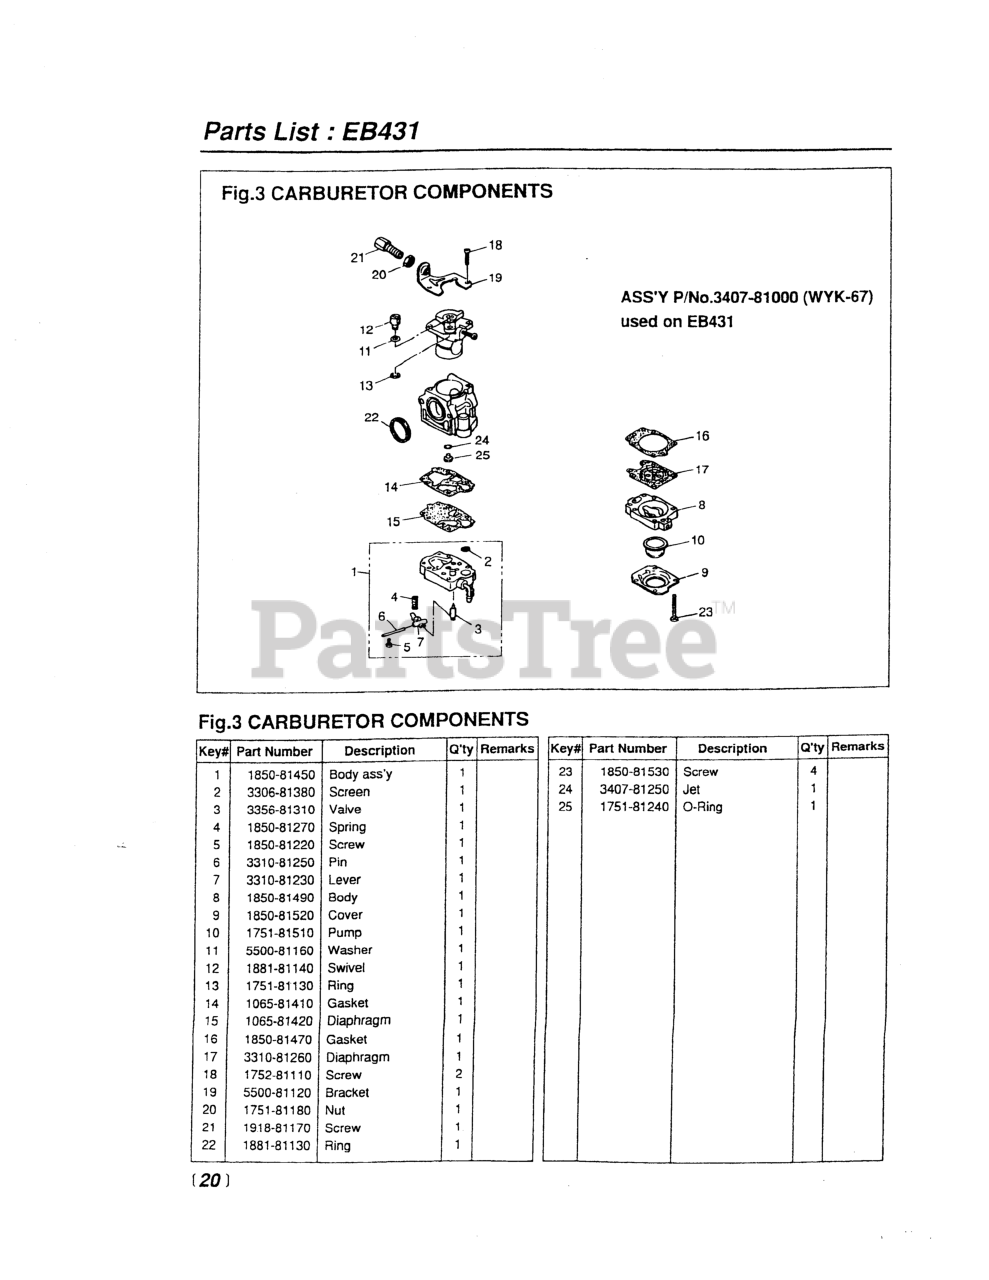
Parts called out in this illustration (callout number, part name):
1	BODY, PUMP
3	VALVE, INLET
4	SPRING, METERING LEVER
5	SCREW, METERING LEVER PIN
6	PIN, METERING LEVER
7	LEVER
8	BODY, PURGE
9	COVER, PUMP
10	PUMP, PRIMING
11	WASHER
12	SWIVEL
13	RING
14	GASKET, PUMP
15	DIAPHRAGM
16	GASKET, DIAPHRAGM
17	DIAPHRAGM (USE 4810-81260)
18	SCREW
20	NUT, CABLE ADJUSTER
21	SCREW, CABLE ADJUSTER
22	RING, PACKING
23	SCREW
25	RING, O
NI	CARBURETOR ASSEMBLY
